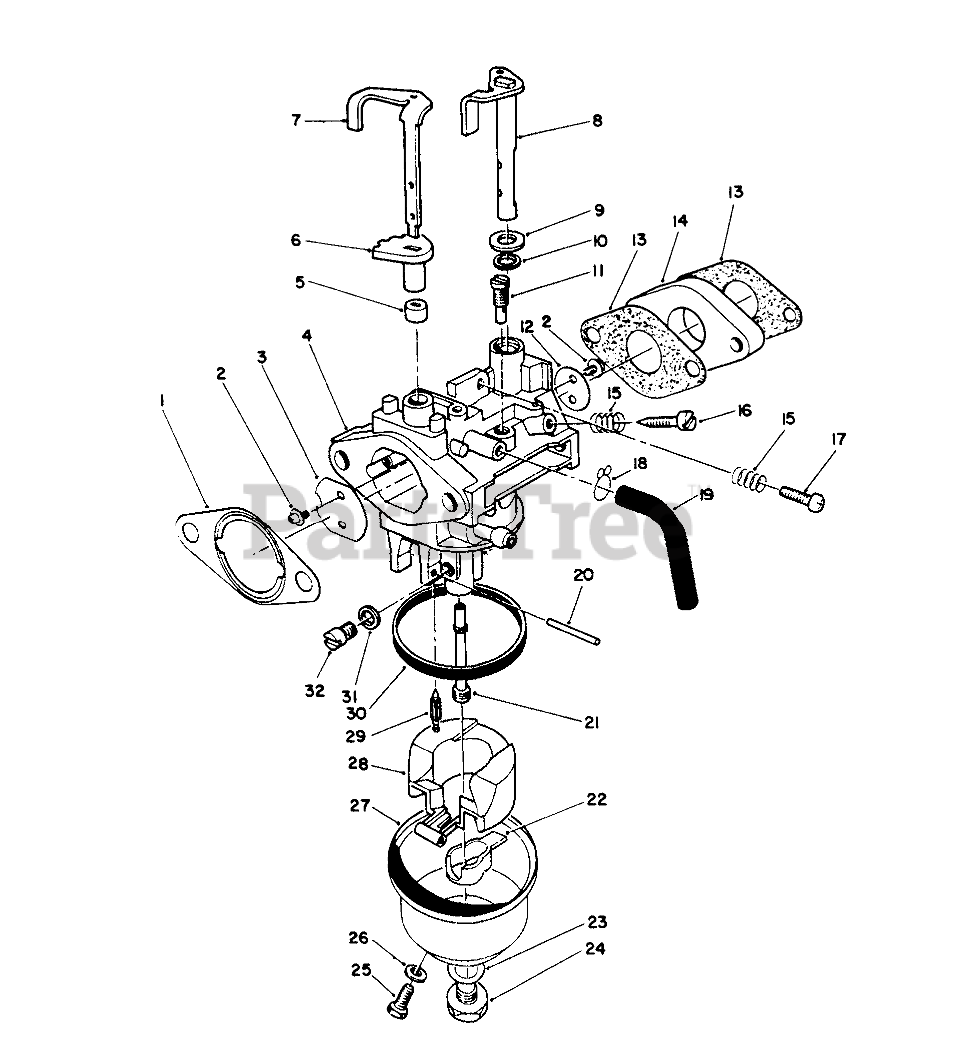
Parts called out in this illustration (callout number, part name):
1	GASKET F/W ENGINE
2	Screw
3	VALVE
4	Body-Carburetor
5	LOWER CHOKE RING
6	UPPER CHOKE RING
7	Shaft-Choke Valve
8	SHAFT
9	WASHER
10	Seal-Throttle Shaft
11	JET - PILOT
12	VALVE
13	GASKET INTAKE
14	INSULATOR - CARB.
15	SPRING-PILOT SCREW
16	ADJUSTER
17	SCREW
18	CLAMP
20	Pin
21	NOZZLE - MAIN
22	SPACER
23	GASKET
24	SCREW
25	SCREW
26	GASKET
28	FLOAT
29	NEEDLE
30	FLOAT BOWL GASKET
31	SPACER
32	JET - MAIN
